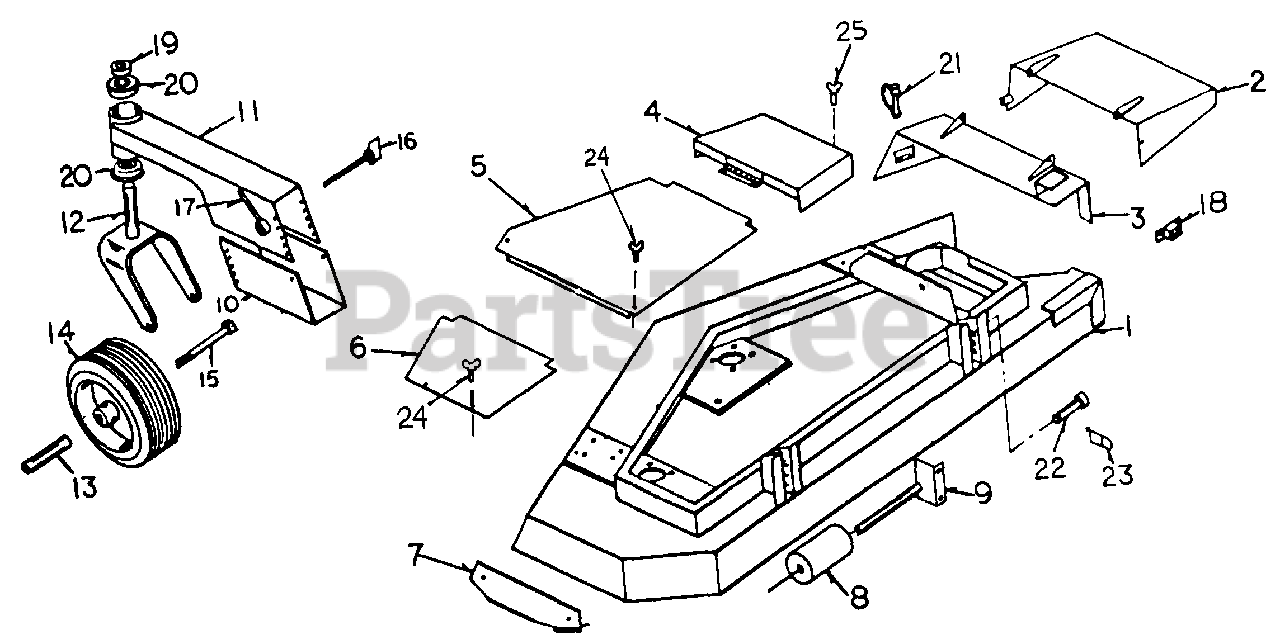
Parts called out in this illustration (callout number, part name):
3	Foot Guard Mount
8	Anti-scalp Roller
9	Shaft & Bracket
10	Gauge Wheel Mount Bracket
11	Gauge Wheel Mount
13	Axle
14	Gauge Wheel Assembly
18	10 Amp Circuit Breaker
19	Set Collar, 1"
23	Hair Pin Cotter
24	Thumb Screw, 1/4-20 x 1/2"
25	Wing Screw, 1/4-20 x 1"
